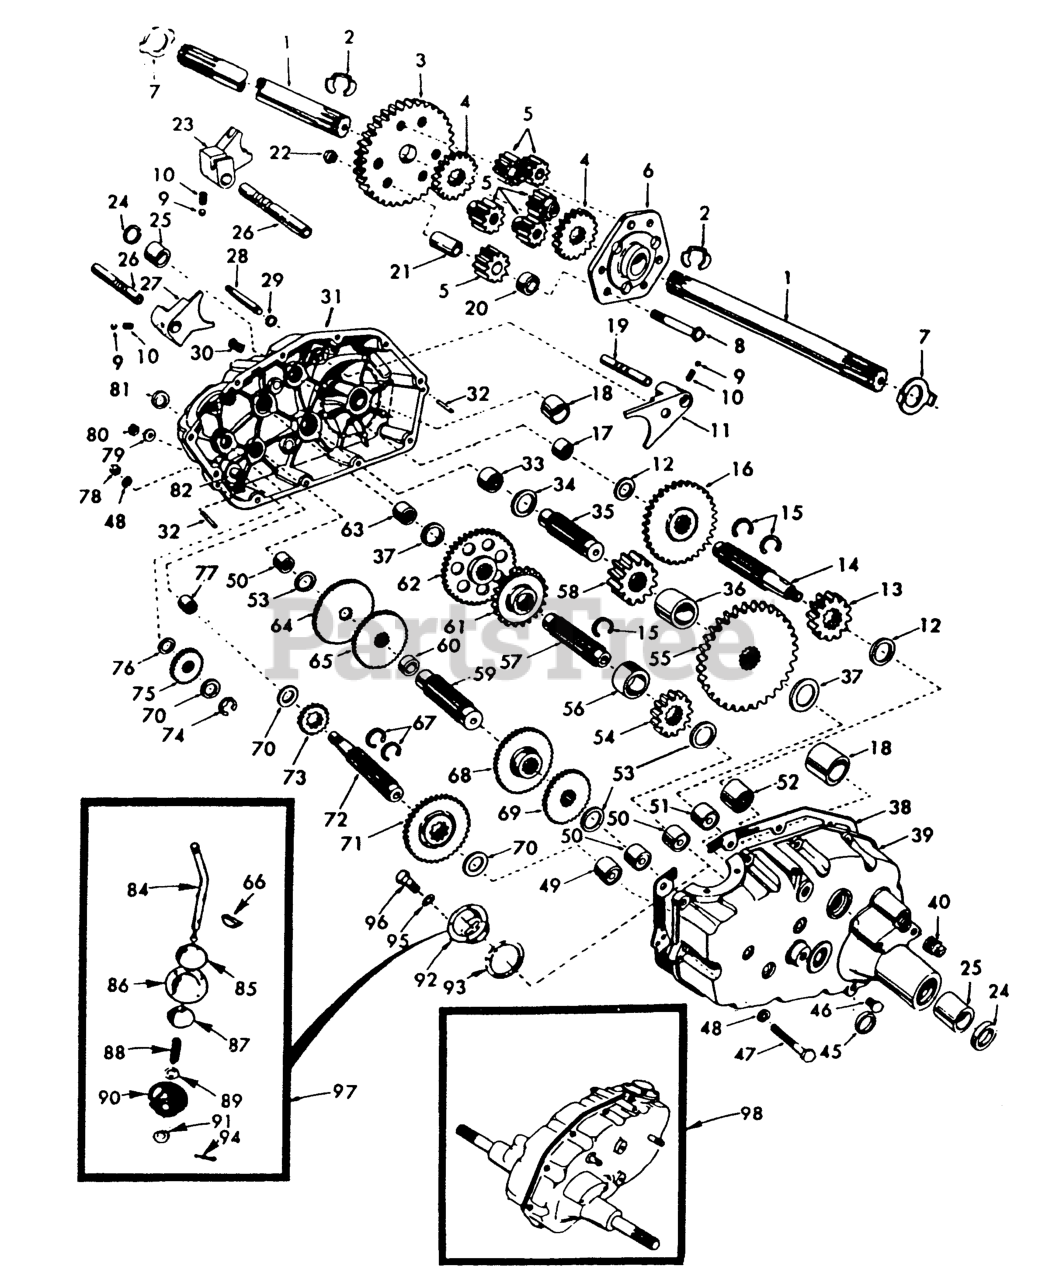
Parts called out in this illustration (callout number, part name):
1	AXLE SHAFT T
2	Retaining Ring
3	FINAL GEAR T
4	DIFF GEAR T
5	DIFF PINION T
6	DIFF CARRIER T
7	WASHER T
8	Hex Bolt 3/8-24 x 3-1/4 (1" Thread Length)
9	STEEL BALL KIT
10	SPRING T
12	THRUST WASHER
13	RED PINION T
14	GEAR SHAFT T
15	SNAP RING T
16	GEAR T
18	BEARING
21	PINION RS
22	GRIPCO NUT
23	SHIFT FORK T
24	OIL SEAL STD
25	BRNG. T
26	SHAFT T
28	SHIFT SHAFT
29	SEAL.OIL.SHAFT.SHIFT.T
31	GEARCASE RH
33	NEEDLE BRNG T
34	WASHER RACE BEARING THRUST
35	GEAR SHAFT T
36	GEAR SPACER T
39	GEARCASE LH
40	Pipe Plug 1/2-14 N.P.T.
47	HEX BOLT
48	LOCKWASHER
49	BEARING TI
50	NEEDLE BRNG T
51	NEEDLE BRNG T
52	BEARING STD
53	BRNG RACE T
54	RED PINION T
55	RED GEAR T
56	PINION SPACER T
57	GEAR SHAFT T
58	FINAL PINION T
59	GEAR SHAFT T
61	RED PINION T
62	RED GEAR T
64	LOW SPEED GEAR T
65	GEAR.REVERSE.T
67	RING STD (1 2)
68	GEAR.SPEED.INTERMEDIATE.T/A
69	HIGH SPEED GEAR T
70	THRUST WASHER
71	CLUSTER GEAR T
72	INPUT SHAFT T
73	LO SPEED PINION T
74	RETAINING RING LT
75	IDLER GEAR T
78	NUT
80	NUT **
81	SEAL STD
82	SHAFT T
84	GEAR SHIFT LVR T
86	COVER AND PIN T
87	GUIDE BALL T
89	WASHER
90	SEAL.SHIFT
91	Washer 9/16 x 15/16 x 12 Ga
92	GEAR SHIFT GATE T
94	COTTER PIN
95	WASHER.LOCK.HVY.HLCL.SPR.5/16
96	BOLT
97	GEAR SHFT LVR T
98	TRANSAXLE ASM
